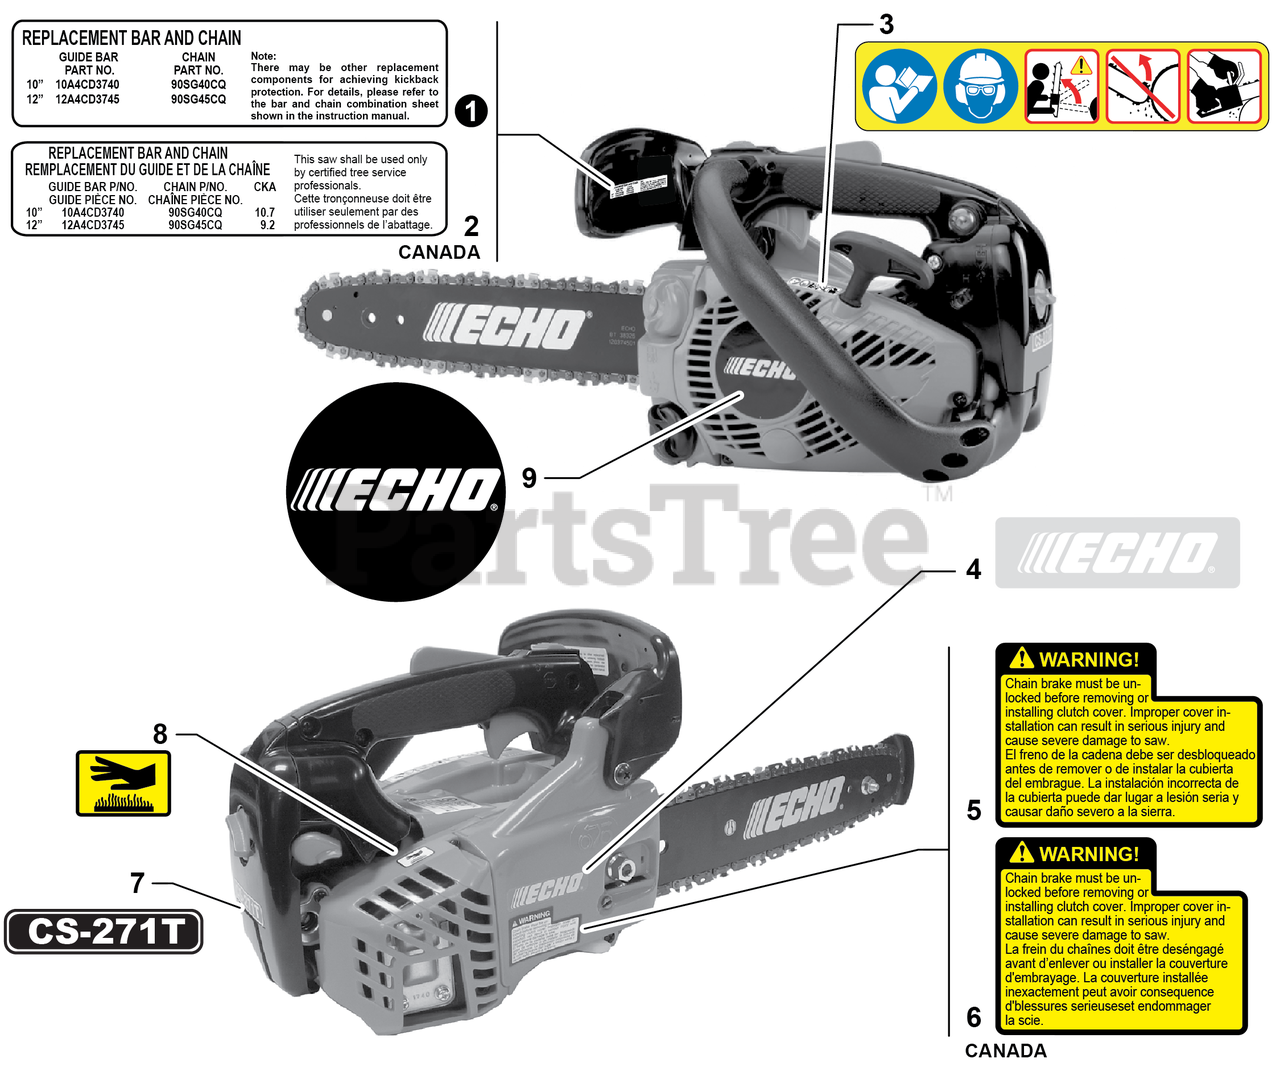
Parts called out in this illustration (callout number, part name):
1	LABEL, BAR & CHAIN
2	LABEL, BAR & CHAIN
3	LABEL, CAUTION
4	LABEL, ECHO
5	LABEL, WARNING
6	LABEL, WARNING
7	LABEL - MODEL CS-271T
8	LABEL, CAUTION - HOT
9	LABEL, ECHO
